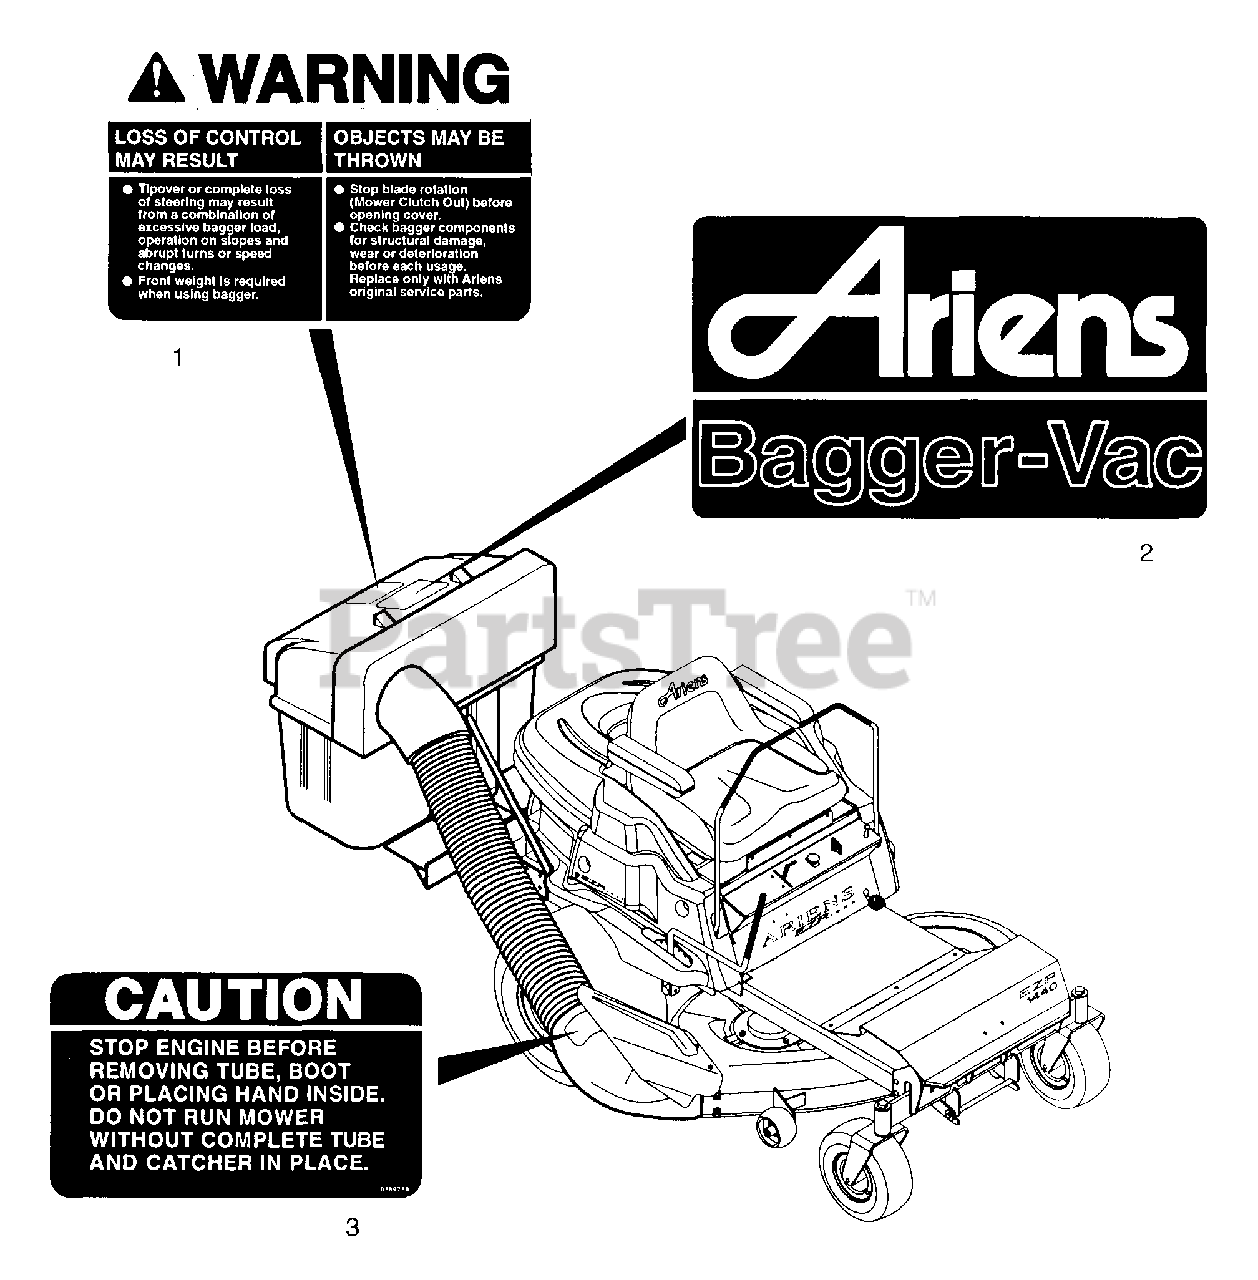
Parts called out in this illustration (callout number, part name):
1	DECAL, WARNING EZR BAGGER
2	DECAL-BAGGER VAC
3	DECAL-BOOT CAUTION
